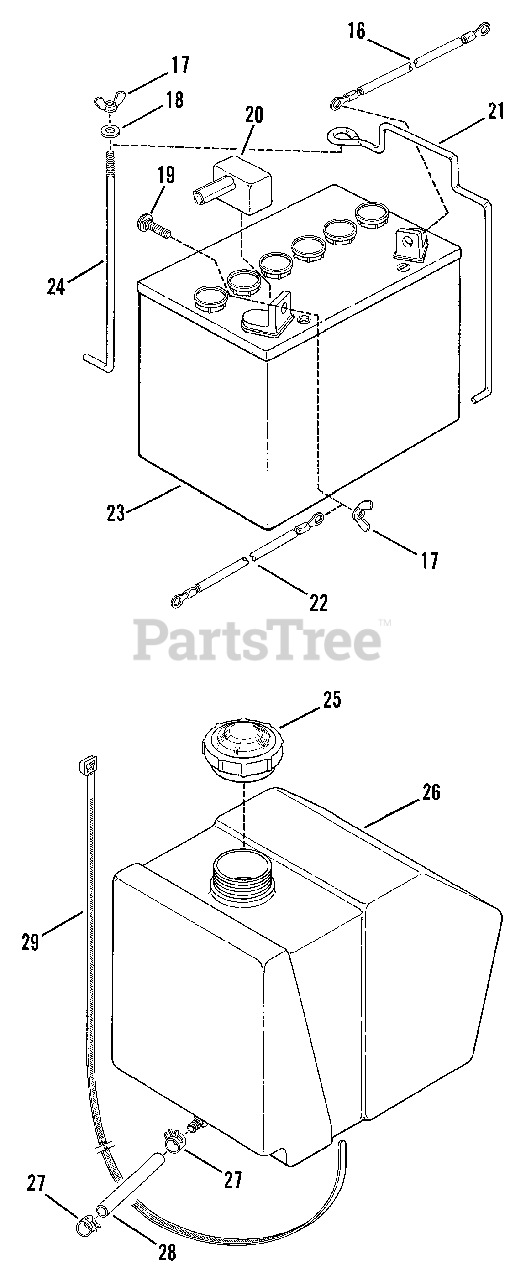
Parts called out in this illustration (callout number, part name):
16	CABLE, Negative Terminal
17	WING-NUT, 1/4-20
18	WASHER, 1/4 SAE
19	BOLT, 1/4-20x3/4" Short Neck Carr.
20	COVER, Positive Terminal
21	CLAMP, Battery
22	CABLE, Positive Terminal
23	BATTERY, 12V., 21 Amp Hour
24	HOLD-DOWN, Battery
25	CAP, Fuel Tank
26	TANK, Fuel
27	CLAMP, Fuel Line
28	LINE, Fuel (3" Long)
29	CABLE-TIE, Fuel Tank Hold-Down
